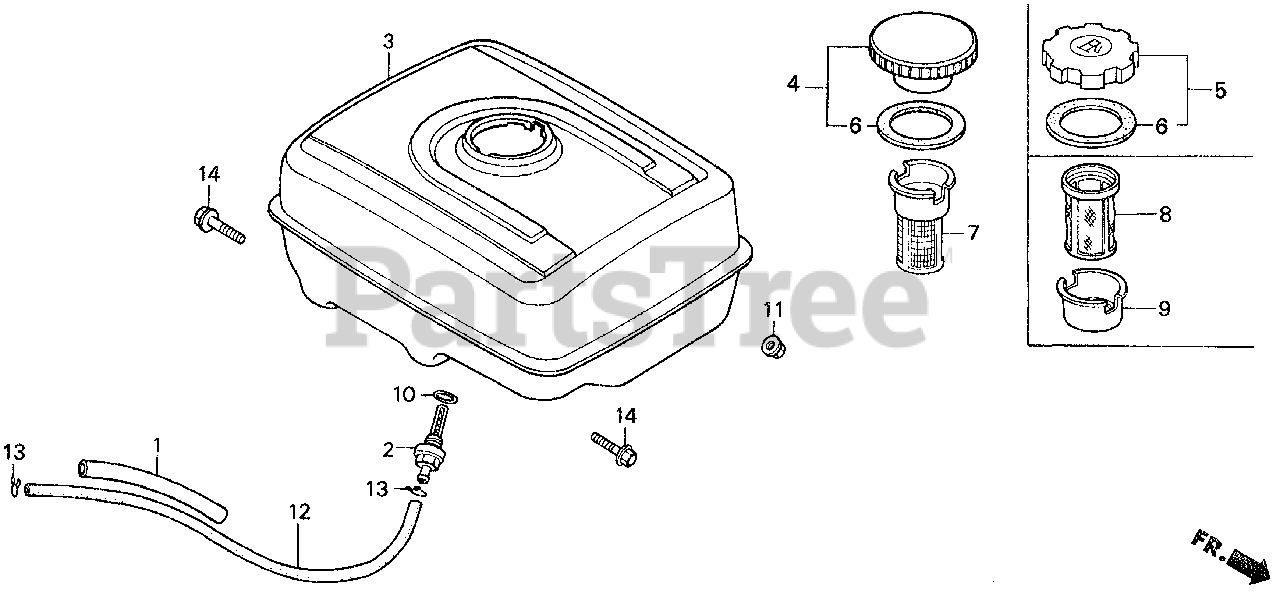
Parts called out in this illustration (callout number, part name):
1	RUBBER, SUPPORTER (107MM)
2	JOINT, FUEL TANK
3	TANK, FUEL *NH31* (MCKINLEY WHITE)
3	TANK, FUEL *NH1* (BLACK)
4	CAP, FUEL FILLER
5	CAP, FUEL FILLER
6	GASKET, FUEL FILLER CAP
7	FILTER, FUEL
8	FILTER, FUEL
9	HOLDER, FUEL FILTER
10	O-RING (13.5X1.5) (ARAI)
11	NUT, FLANGE (8MM)
12	BULK HOSE, FUEL (4.5X3000) (4.5X235)
13	CLIP, TUBE (B8)
14	BOLT, FLANGE (8X25)
